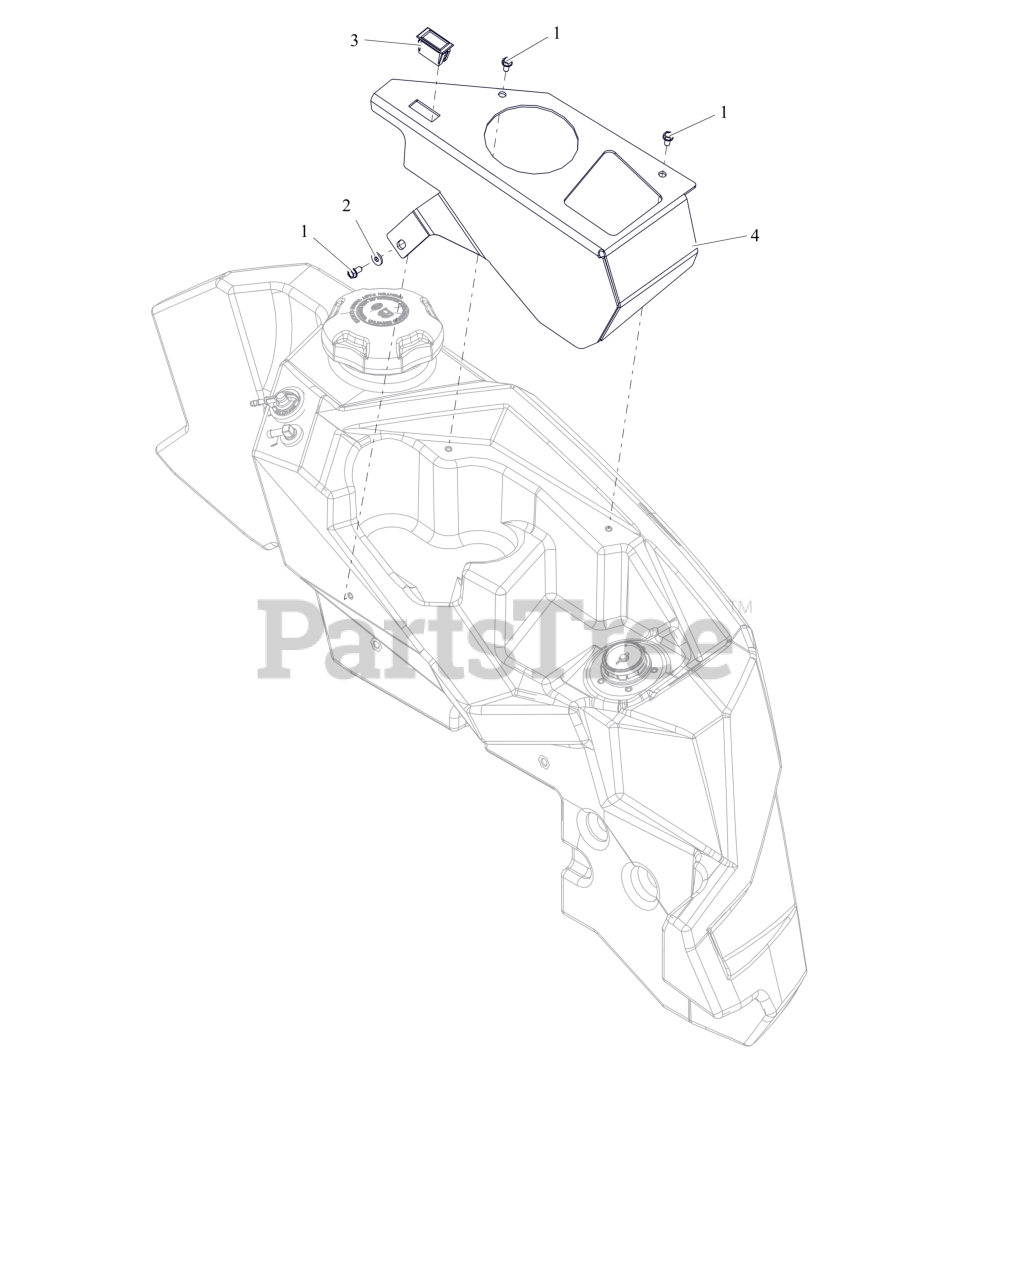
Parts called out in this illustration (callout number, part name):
1	SCR-MCH 10-24X.38 HWHSTAINLESS
2	WSHR-FL-STL .196X.50X.06 ZC120
3	SWITCH,BLANK
4	PANEL- LH CONTROL (RED)
